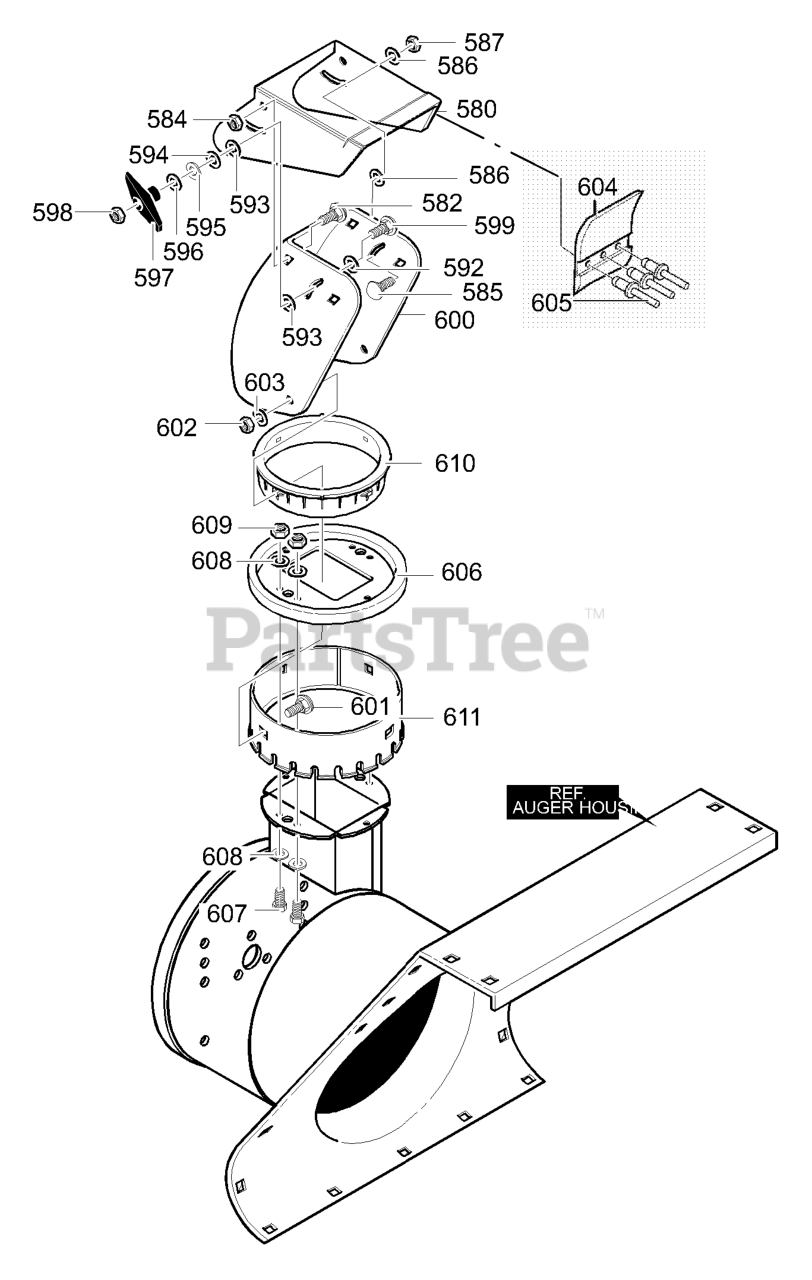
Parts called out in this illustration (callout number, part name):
580	CHUTE, UPPER RH CONTROL
584	LOCKNUT
586	WASHER, PLASTIC
587	LOCKNUT
592	WASHER, PLASTIC
593	WASHER, PLASTIC
594	WASHER, FLAT
595	WASHER
596	WASHER, FLAT
597	T-KNOB
598	HEXNUT
600	ASSEMBLY, CHUTE
602	LOCKNUT
603	WASHER, FLAT
604	FLAP, CHUTE INSERT
605	RIVET, POP ALM .125 X .23
607	BOLT, CARR.1/4-20 x1.00
608	WASHER, FLAT
609	LOCKNUT
610	RETAINER RING, INNER
611	RETAINER RING, OUTER
